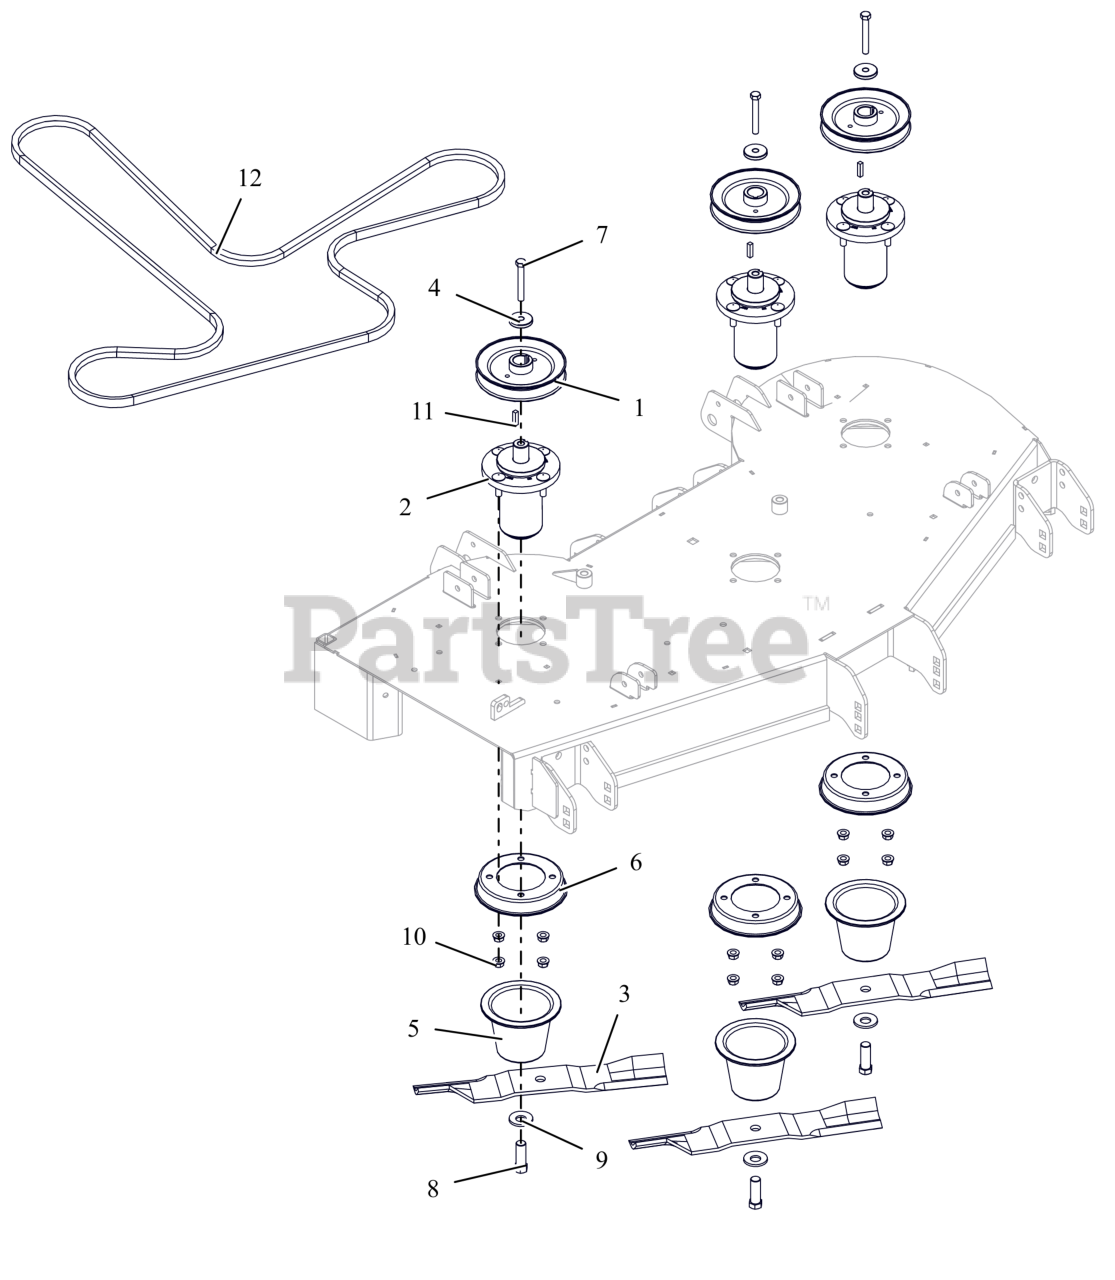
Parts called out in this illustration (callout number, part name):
1	PULLEY, V-1.00 ID X 5.75 OD (BLACK)
2	ASM, MAINT FREE ALUM SPINDLE
3	BLADE, 16.19" MOWER (HI-LIFT)
4	RETAINER, SHEAVE
5	GUARD, SPINDLE LOWER
6	GUARD, SPINDLE TOP
7	BLT, HEX .38-16X2.75 G8 ZCC
8	BLT, HEX .62-18X1.75 G8 ZCC
9	WSHR-BLVL .669X1.535X.138
10	NUT-LK-CTR-FLG .375-16 GF ZCC
11	KEY, SQ .25X.25X1.00 RC 40-50
12	V-BELT, B RAW EDGE EPDM
